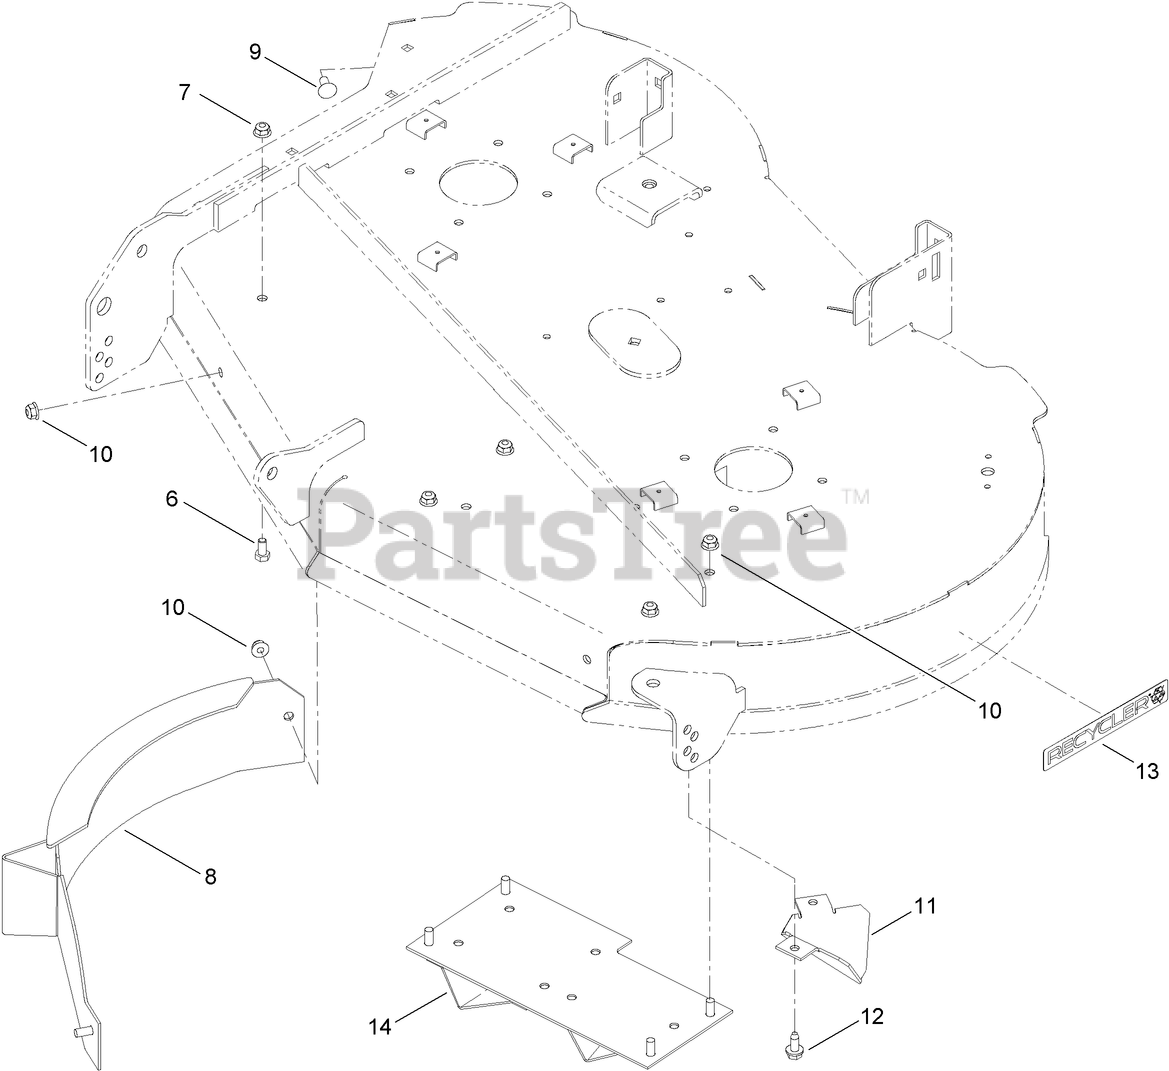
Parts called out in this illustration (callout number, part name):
6	SCREW-HH
7	NUT-HF, NI
8	BAFFLE ASM
9	BOLT-CARR
10	NUT-HF, NI
11	KICKER-FLANGED
12	SCREW-HWHTF
13	DECAL-RECYCLER
14	KICKER ASM
